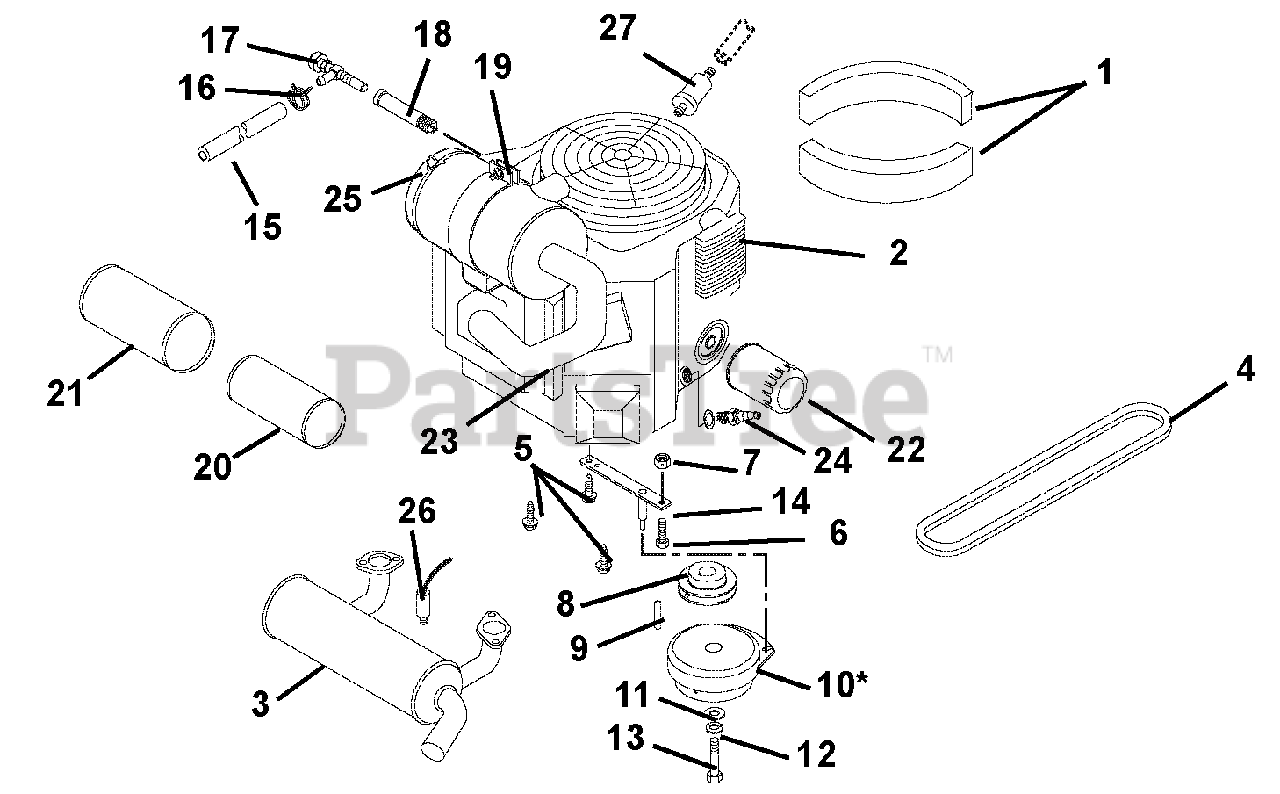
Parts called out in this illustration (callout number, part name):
1	Seal, Foam
2	Engine, Kohler 28HP EFI (048, 069)
3	Muffler, Kohler EFI (048, 069)
4	Belt, Poly-V
5	Screw, Tapping Hex Washer Head .38-16 x 1.00
6	Bolt, Hex .31-18 x 1.75 Grade 5
7	Nut, Locking Top Flange .31-18
8	Sheave, Poly V 1.127 x 3.25
9	Key, Square .25 x 1.00 x .25
10	Clutch, Electric
11	Washer, Flat Steel .515 x 1.625 x .250
12	Washer, Locking .44 x .109
13	Bolt, Hex .44-20 x 3.00 Grade 5
14	Anchor, Clutch
15	Gas Line, Bulk .25 ID (045, 046, 047, 049, 052, 053, 066, 067, 068, 070, 071, 072)
16	Hose, Clamp
17	Cock, Oil Drain
18	Adapter, Oil Drain
19	Bracket, Air Cleaner Mount
20	Element, Inner Safety
21	Element, Outer Primary
22	Oil Filter (047, 048, 052, 053, 068, 069, 071, 072)
23	Hose, Air Intake (047, 048, 052, 053, 068, 069, 071, 072)
24	Spark Plug (047, 048, 052, 053, 068, 069, 071, 072)
25	Assembly, Air Cleaner
26	Sensor, Oxygen (048, 069)
27	Fuel Filter (045, 046, 049, 066, 067, 070)
